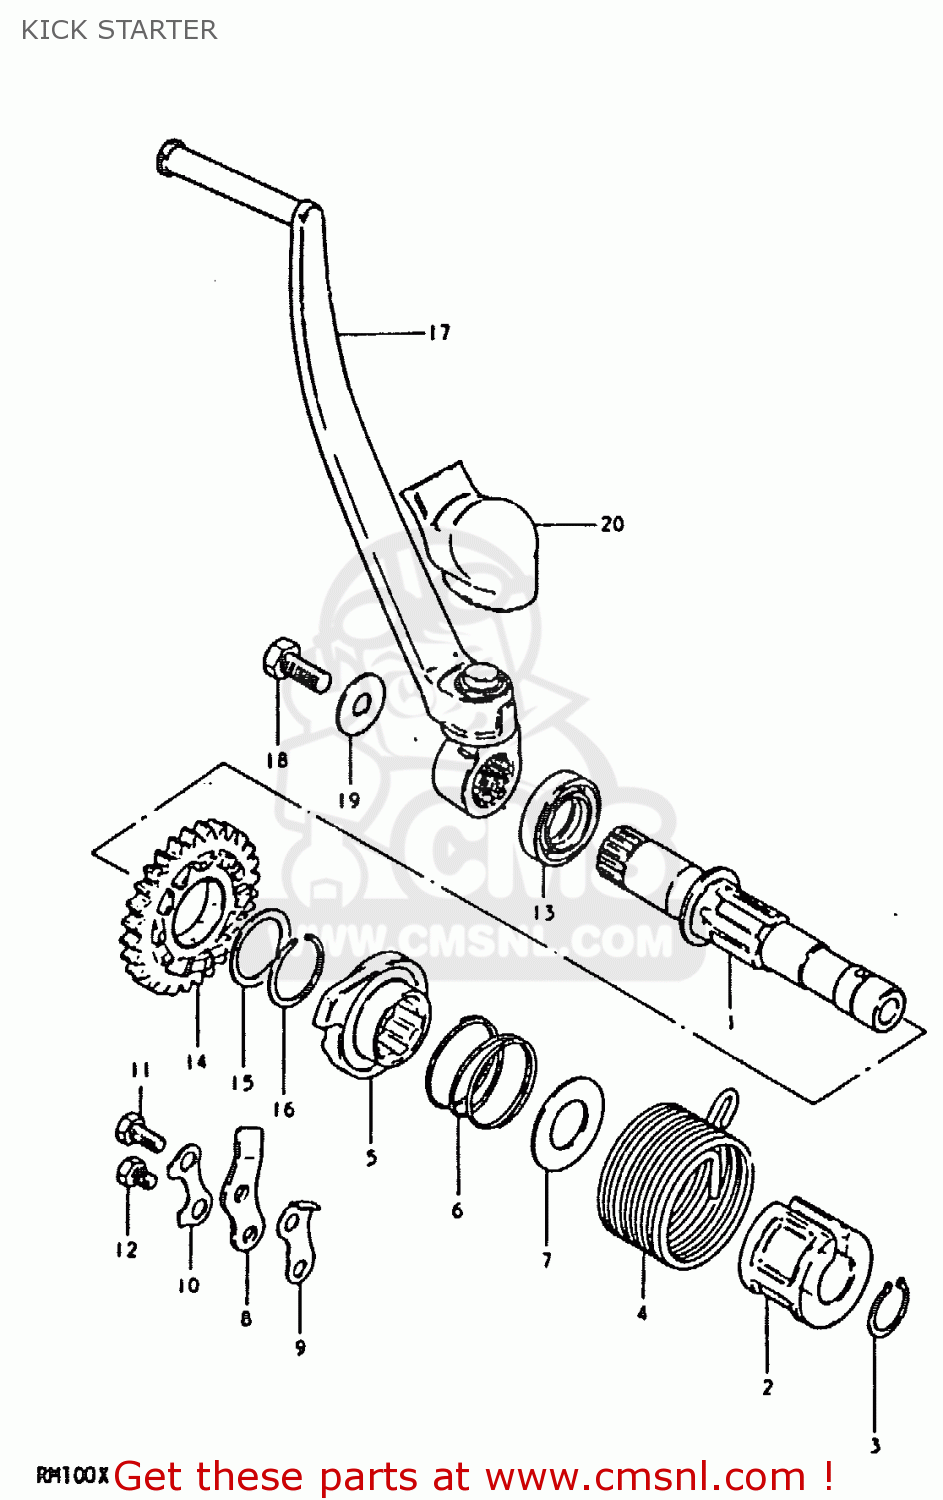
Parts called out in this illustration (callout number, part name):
1	SHAFT,KICK STARTER
2	GUIDE,KICK STARTER SFT SPRING
3	CIRCLIP
4	SPRING
5	STARTER,KICK
6	SPRING
7	WASHER
8	GUIDE,KICK STARTER
9	STOPPER,KICK STARTER
10	WASHER
11	BOLT, UPPER
12	BOLT
13	SEAL,OIL(20X27X5)
14	GEAR,KICK STARTER DRIVE
15	SHIM
16	O-RING
17	LEVER ASSEMBLY,KICK STARTER
18	BOLT
19	WASHER(8.2X23X3.2)
20	COVER,KICK LEVER JOINT
